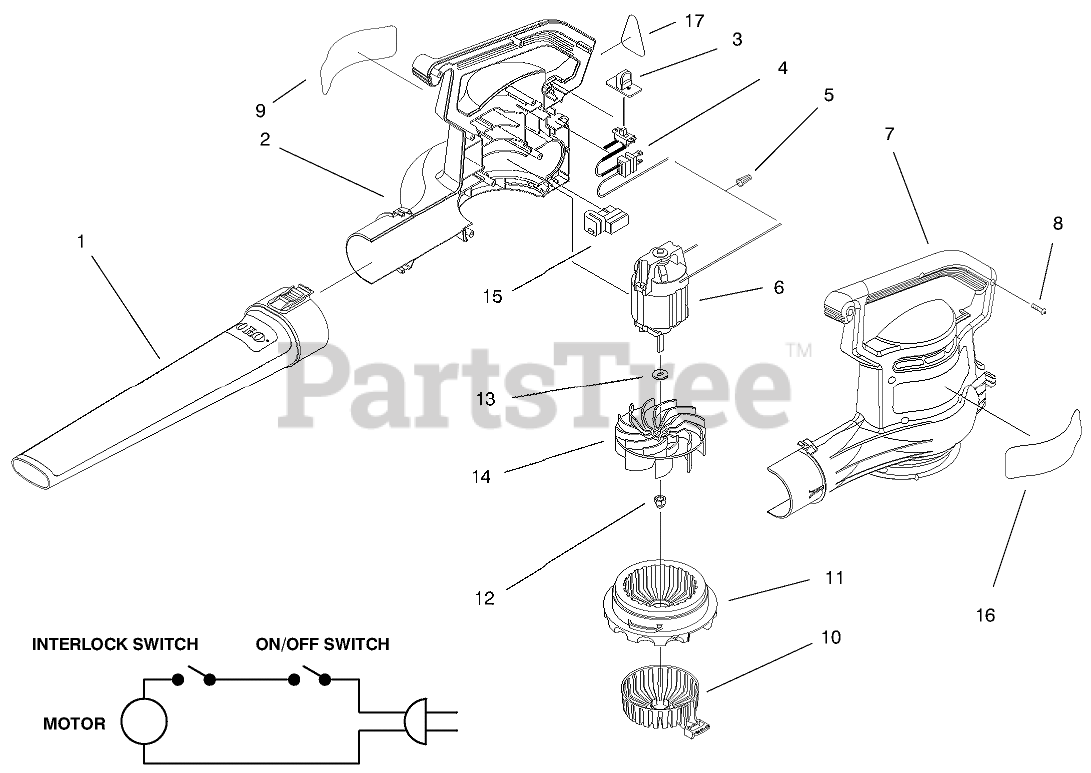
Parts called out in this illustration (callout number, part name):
1	TUBE - BLOWER SHORT
2	HOUSING, RH (RED)
3	COVER-SWITCH
4	HARNESS ASSEMBLY
5	CONNECTOR-NUT, WIRE
6	MOTOR, ES-40, MID-BLOWER
7	HOUSING, LH (RED)
8	SCREW-PPH
9	DECAL-LOGO
10	CHOKE - AIR, GREY
11	COVER - INLET, W/HOLE
12	NUT-HEX
13	WASHER
14	IMPELLER, BLOWER
15	SWITCH, INTERLOCK
16	Decal-Warning
17	DECAL - INFORMATION
